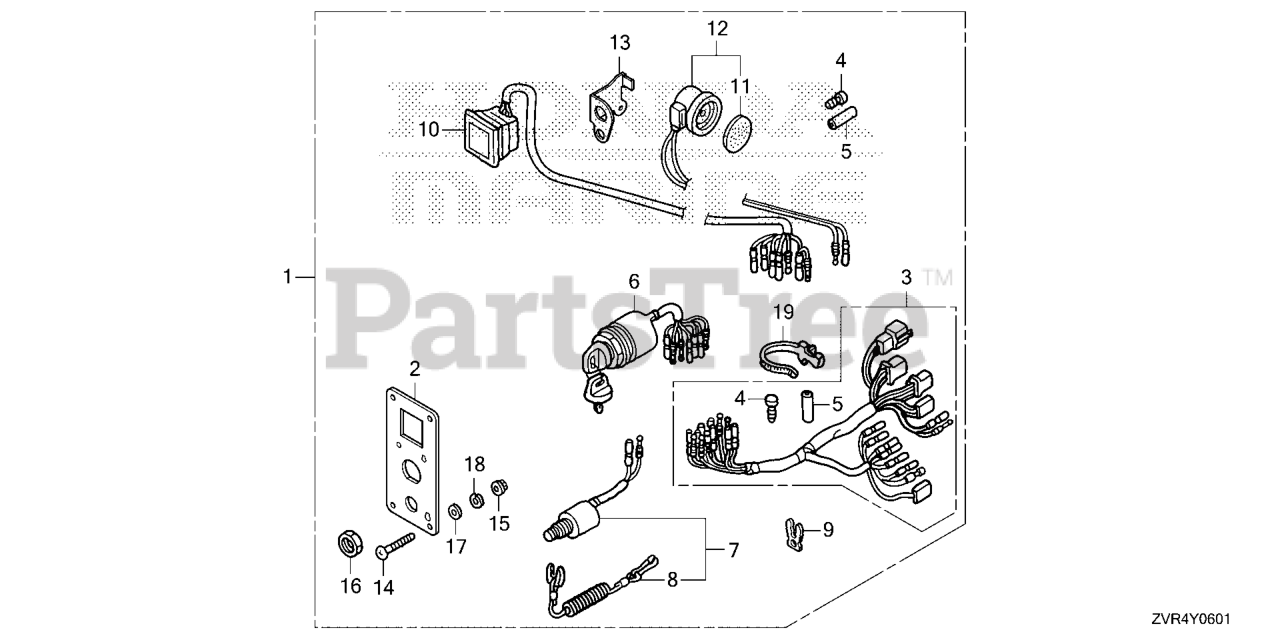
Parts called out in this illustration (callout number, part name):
1	PANEL KIT, SWITCH (4-LED)
2	PANEL, CONTROL
3	HARNESS ASSY., SWITCH PANEL
4	PLUG, CONNECTOR (INNER) (TROLLING CONTROL)
5	PLUG, CONNECTOR (OUTER) (ENGINE NO.)
6	SWITCH ASSY., COMBINATION (SINGLE) (DUAL)
7	SWITCH ASSY., EMERGENCY STOP
8	WIRE, EMERGENCY (SINGLE) (DUAL)
9	CLIP, EMERGENCY LOCK
10	LAMP ASSY., INDICATION (4-LED)
11	PLATE, TURN SIGNAL BUZZER DUAL QTY = (2) (SINGLE)
12	BUZZER, WARNING DUAL QTY = (2) (SINGLE)
13	BRACKET, BUZZER
14	SCREW, PAN (5X40) DUAL QTY = (8) (SINGLE)
15	NUT, FLANGE (5MM)
16	NUT, HEX. (16MM) DUAL QTY = (2) (SINGLE)
17	WASHER, PLAIN (5MM)
18	WASHER, SPG (5MM)
19	BAND, WIRE HARNESS (150MM) (NATURAL) DUAL QTY = (2) (SINGLE)
